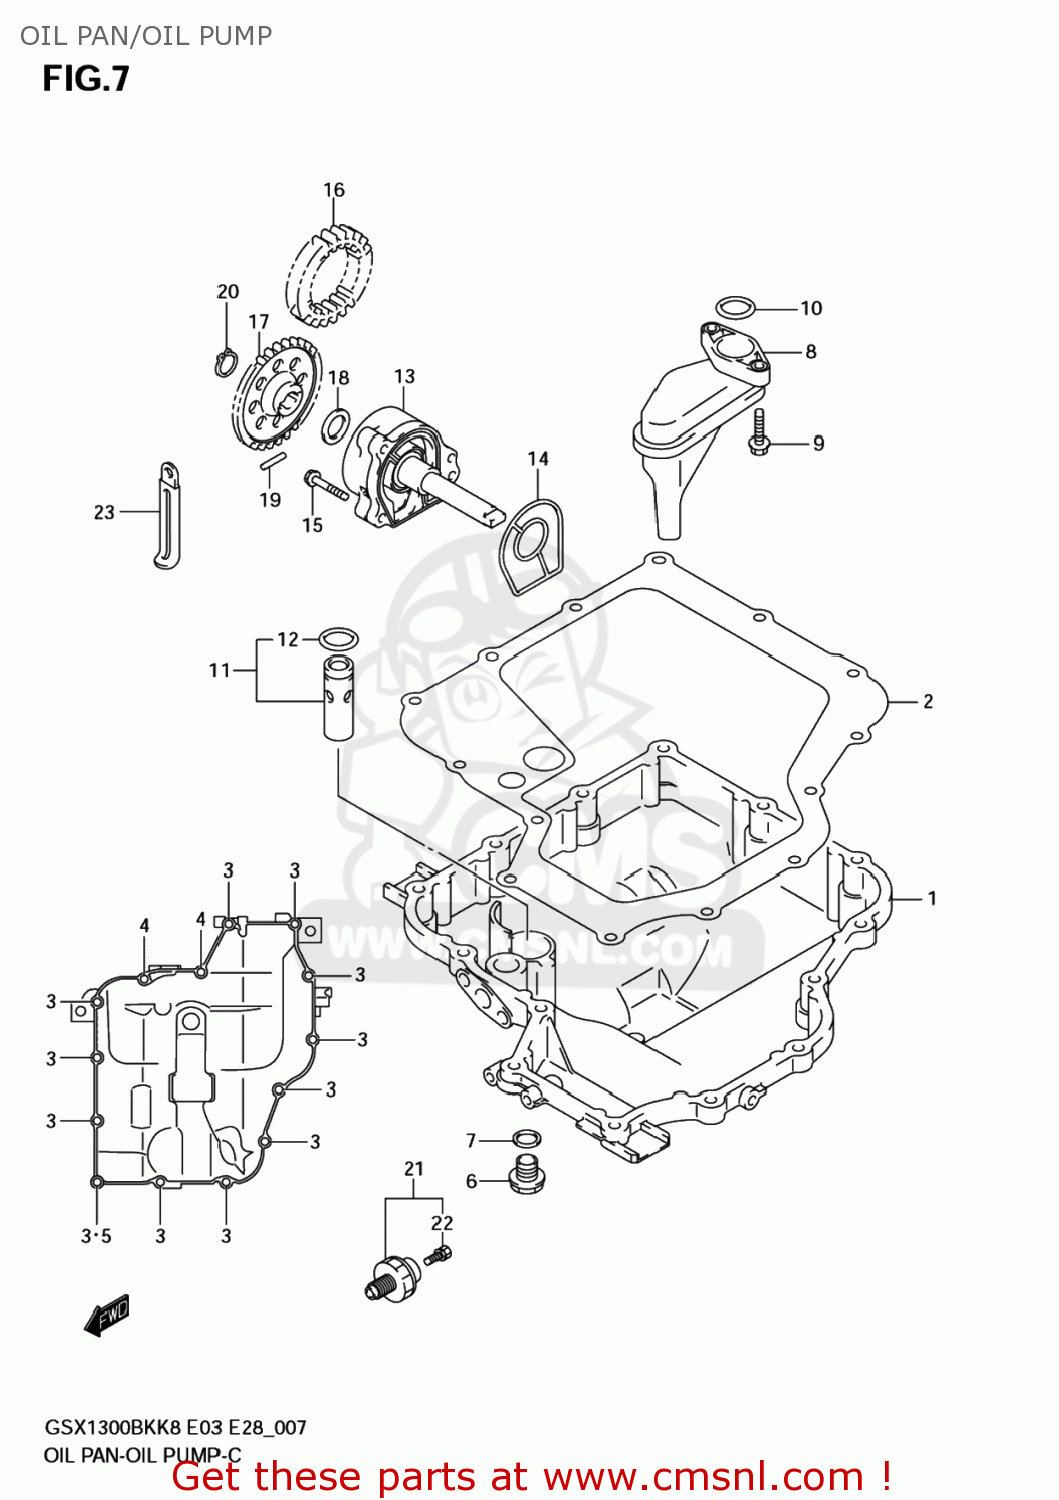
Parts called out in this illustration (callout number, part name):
1	PAN,OIL
2	GASKET,OIL PAN (NAS)
3	BOLT
4	BOLT
5	GASKET(5.8X13X1.2) (NAS)
6	PLUG(14X20)
7	GASKET(13.8X18.8X4.8) (NAS)
8	STRAINER,ENGINE OIL
9	BOLT
10	O RING(D:2.62,ID:20.3)
11	VALVE ASSY,OIL RELIEF(7K)
12	O RING(D:1.9,ID:13)
13	PUMP ASSY,ENGINE OIL
14	O RING,OIL PUMP
15	BOLT
16	GEAR,OIL PUMP DRIVE
17	GEAR,OIL PUMP DRIVEN
18	SHIM(12X20X0.5)
19	PIN(5X18)
20	CIRCLIP,12 MM
21	SWITCH ASSY,OIL PRESSURE
22	BOLT,OIL PRESSURE SWITCH
23	CLAMP(L:45)
